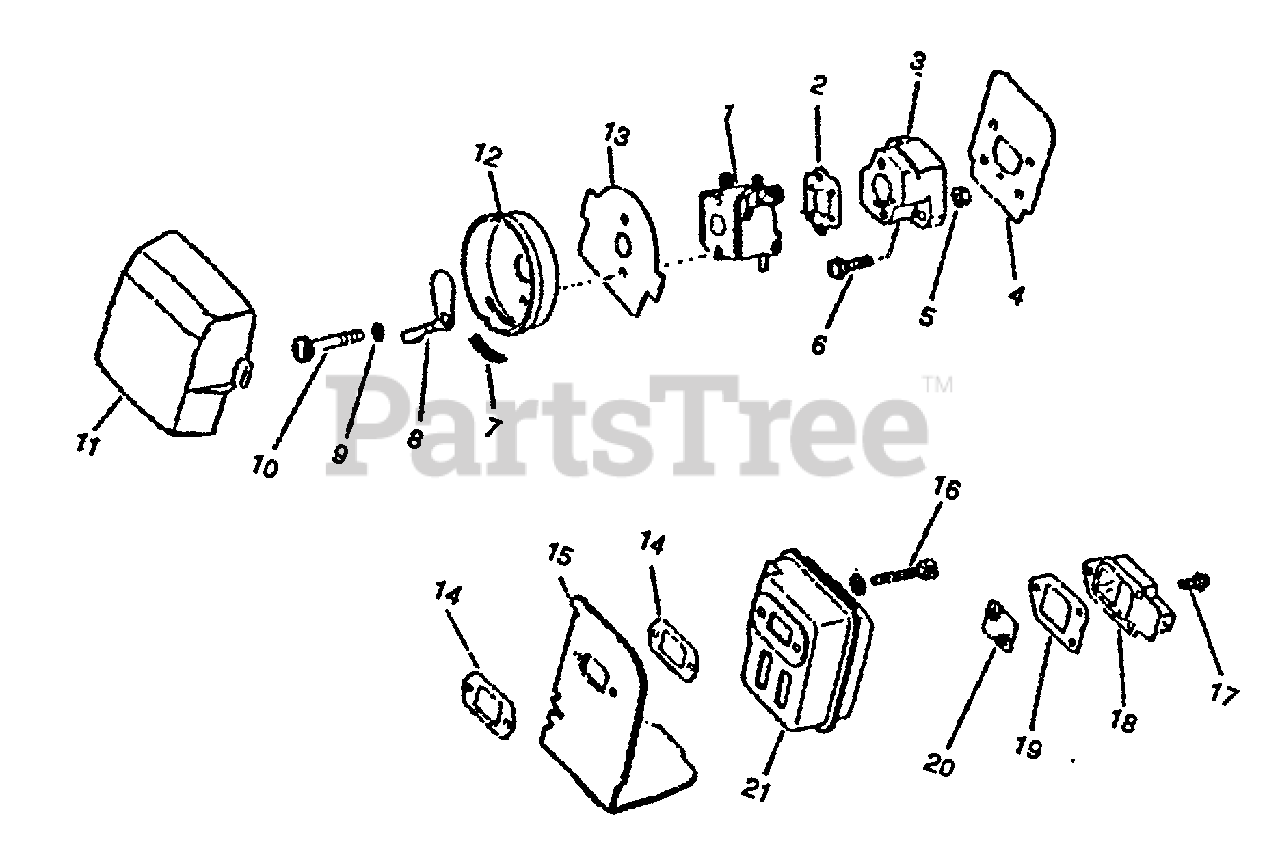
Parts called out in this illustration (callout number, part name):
1	CARBURETOR - C1U-K9
2	GASKET, INTAKE
3	INSULATOR, INTAKE
4	GASKET, INTAKE
5	NUT M5
6	SCREW 5×20
7	BUSHING
8	SHUTTER, CHOKE
9	WASHER 5.2×8×0.8T
10	SCREW 5×57
11	FILTER, AIR
12	CASE, AIR FILTER
13	PLATE, AIR FILTER
14	GASKET, EXHAUST
15	COVER, EXHAUST
16	BOLT 5×55
17	SCREW 4×10
18	GUIDE, EXHAUST - INNER
19	GASKET, EXHAUST
20	SCREEN, SPARK ARRESTER
22	WASHER, FLAT 5.5×10×0.8
